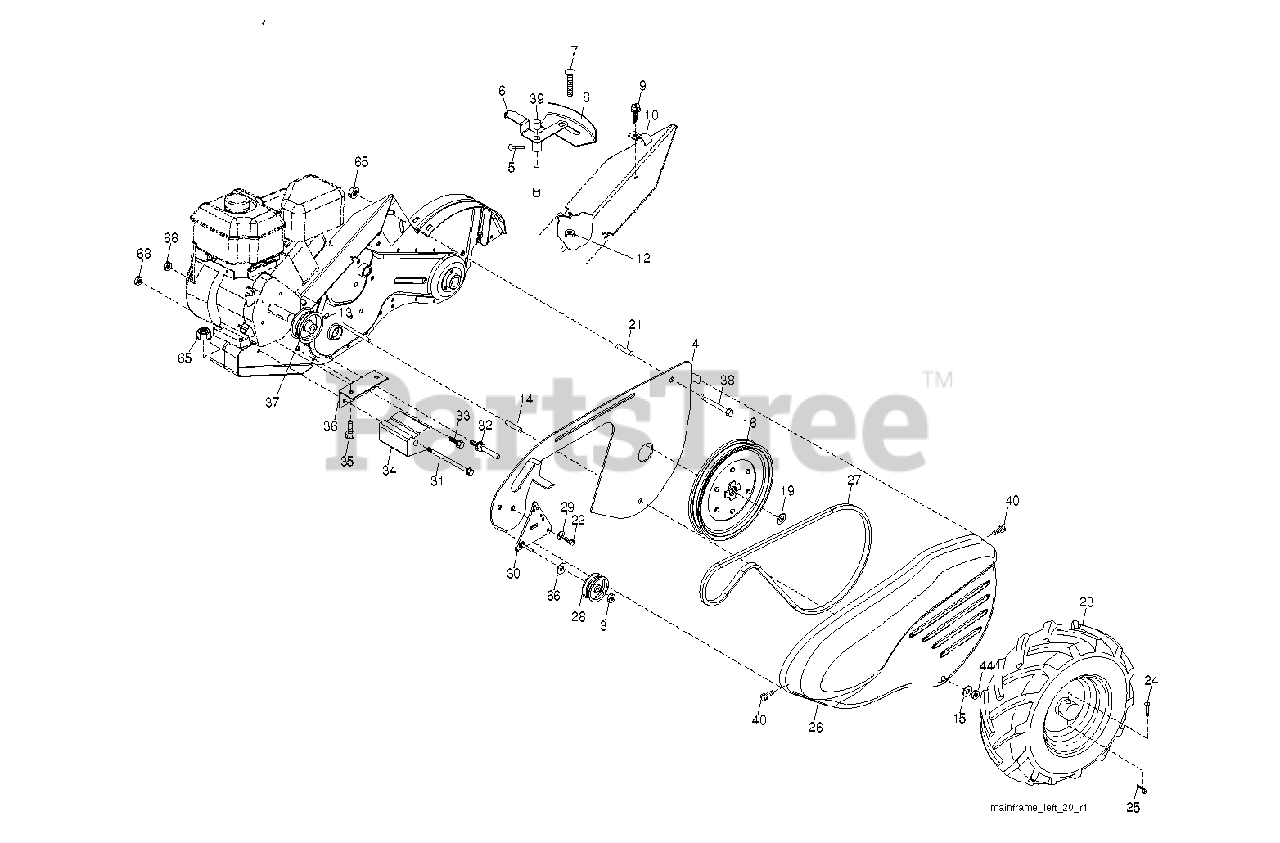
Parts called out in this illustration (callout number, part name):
3	LOCKNUT
4	SHIELD.INNER.BELT.GUARD.RT
5	PIN.SPIROL.FLARED
6	LEVER ASM CRT
9	TAPPING SCREW
10	CONDUIT CLIP T
12	NUT
13	SET SCREW **
14	SPACER-SPLIT.327 X .42
15	WASHER
16	SHEAVE, TRANSMISSION
19	RETAINING RING LT
21	SPACER CRT
24	RIVET,DRILLED
25	RETAINER M
27	V-BELT
28	PULLEY-IDLER TI
29	KLIP RING
30	BRACKET.ASM.IDLER
31	BOLT.FIN.HEX.3/8-16UNC
32	SHIFT ARM CRT
33	BOLT
34	COUNTERWEIGHT.LH.CRT
35	BOLT, HEX 5/16-18X1-3/4
36	BRACKET LH CRT
37	ENGINE PULLEY
38	BOLT
39	CAP.PLUNGER.BLACK
40	SCREW.HEX.WSH.SLT.#10-24X.50
44	NUT.71038.31-18.HEX.NYLOCK
65	LOCKNUT-FLANGE 5/16-18
66	WASHER
